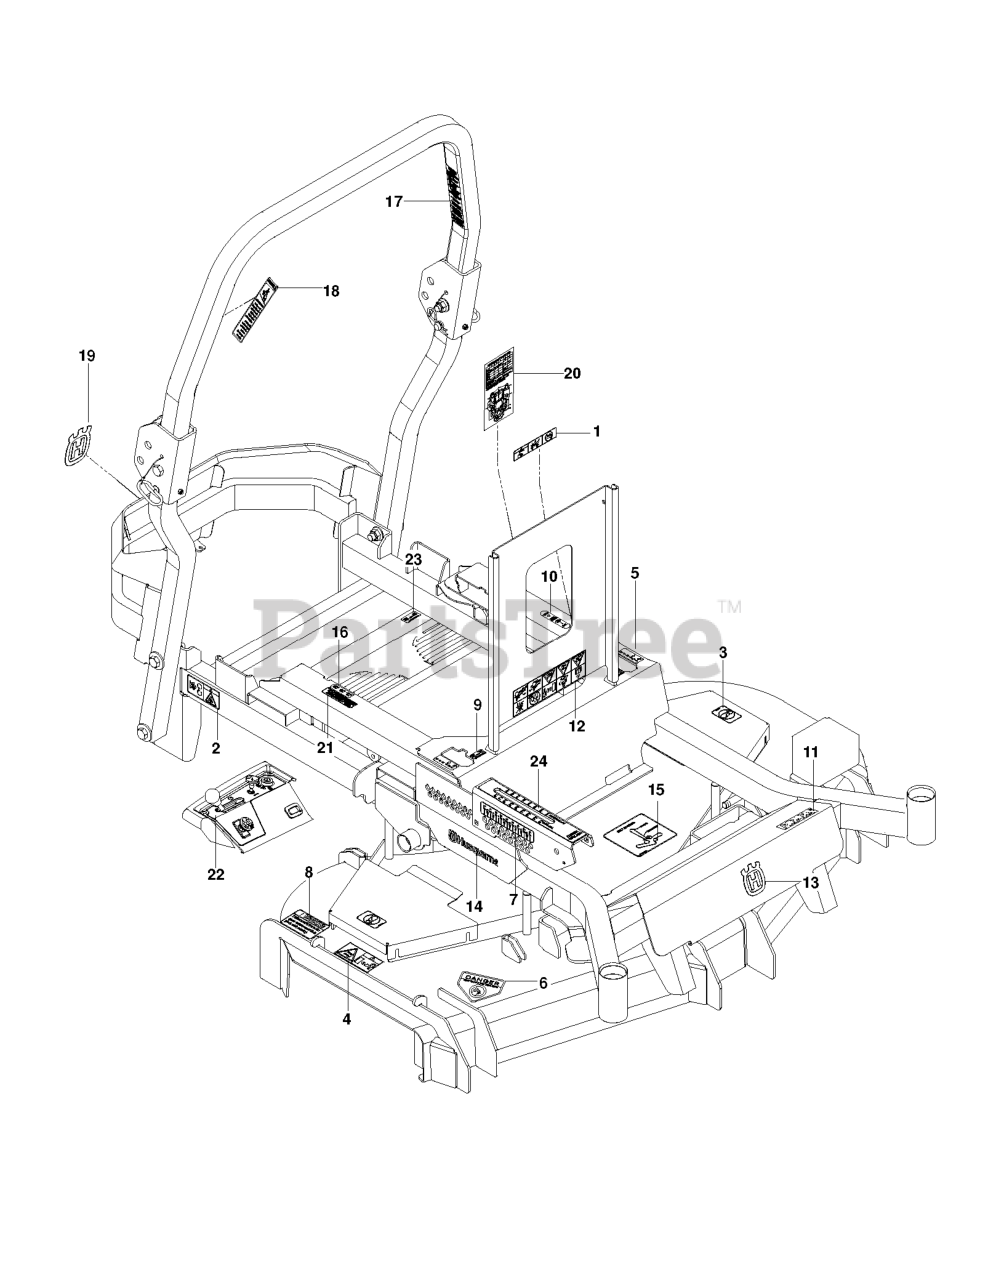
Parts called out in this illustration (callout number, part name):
1	EURO DECAL-BATTERY WARNIN6
2	DECAL, BELT DRIVE
3	DECAL, NO STEP
4	DECAL, EURO SEVERING
5	DECAL, MOTION CONTROL
6	DECAL, CPSC
7	DECAL ZTR PZ60
8	DECAL, CAUTION
9	DECAL, F.S.T.
10	DECAL, PARK BRAKE
11	DECAL, HEIGHT
12	DECAL, WARNING
13	DECAL.AUGER.HUSQ.CROWN.SNOW
14	RP.DECAL.BADGE.170MM.TEXTLOGO
15	DECAL, BELT ROUTING
16	DECAL, FUSE
17	DECAL, ROPS
18	DECAL, ROPS, WARNING
19	DECAL, CROWN H, 110MM
20	DECAL, SERVICE
21	DECAL, WARNING SPARK ARRESTOR
22	DECAL, CONTROL, GAS
23	DECAL, HEIGHT
24	DECAL, FUEL
